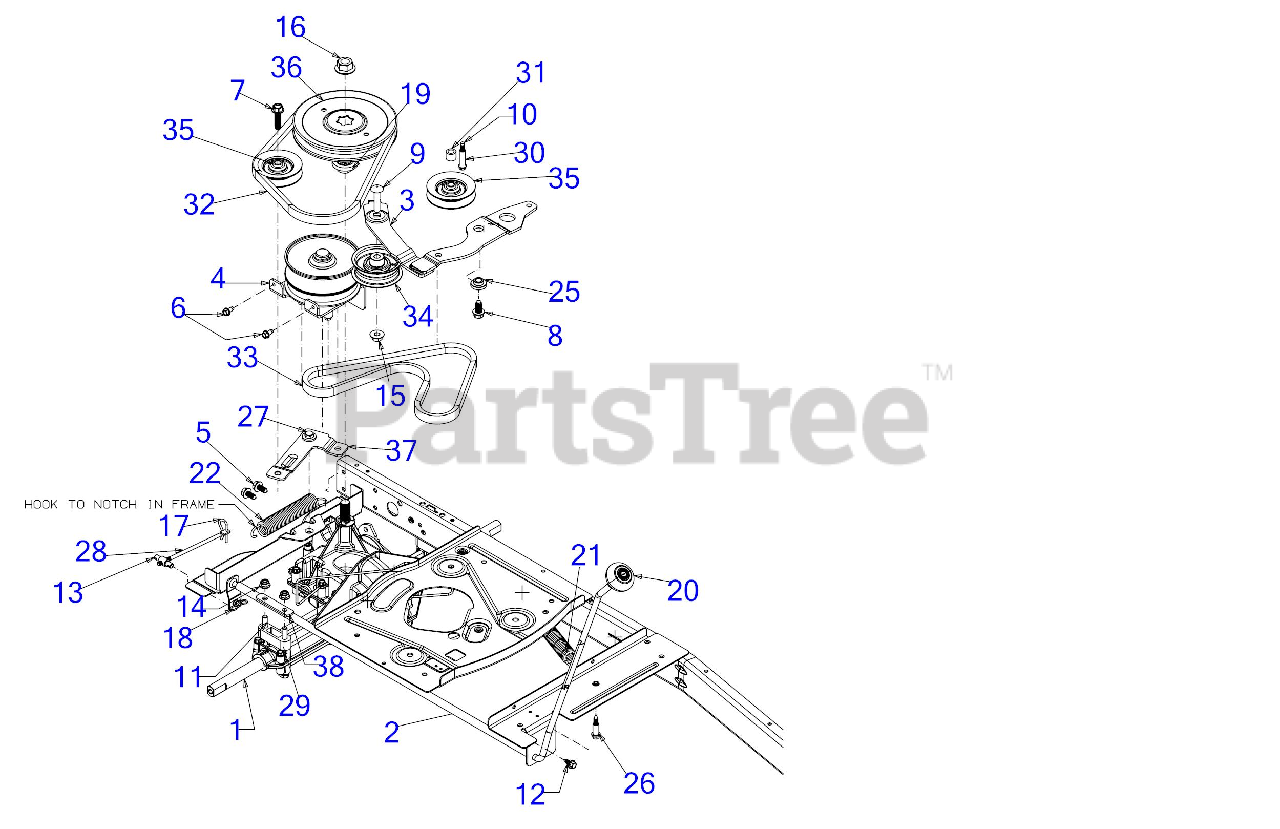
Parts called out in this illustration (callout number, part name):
1	TRANSMISSION ASSEMBLY
2	SHIFT HANDLE ASSEMBLY
3	DRIVE IDLER ASSEMBLY
4	BRACKET ASSEMBLY
5	SCREW 5/16-18 x .750
6	SCREW 1/4-20 X.500
7	SCREW 3/8-16 x 1.375
8	SCREW 3/8-16 x 3/4
9	BOLT 3/8-16 x 1.69 GR5
10	SCREW 1/4-20 x 1.750
11	SCREW 5/16-18X3.5 GR5
12	SCREW 1/4-20X.625
13	ADJUSTUSTMENT FERRULE 1/4-20 x 1.00
14	FLANGE LOCK NUT 5/16-18
15	FLANGE LOCK NUT
16	FLANGE NUT W/HUB
17	COTTER PIN
18	BOW TIE COTTER PIN 1/4-5/16
19	PULLEY HUB
20	SHIFT KNOB
21	EXTENSION SPRING .94 x 6.74
22	EXTENSION SPRING (.99 x 6.18)
25	SHOULDER SPACER 1.00 x .38 x .38
26	SHOULDER SCREW .368 x .75 x 1/4-20
27	SHOULDER SCREW .560X.165
28	SHIFT ROD
29	TRANSAXLE SPACER
30	SPACER:.260 x .372 x 1.420
31	SPACER
32	V-BELT 5L x 35.25
33	V-BELT 5L x 35.25
34	FLAT IDLER PULLEY 2.75 OD
35	V-IDLER PULLEY A x 3.06 OD
36	V-TYPE PULLEY 6.56" DIA
37	IDLER BRACKET REAR
38	TRANSAXLE BRACKET
